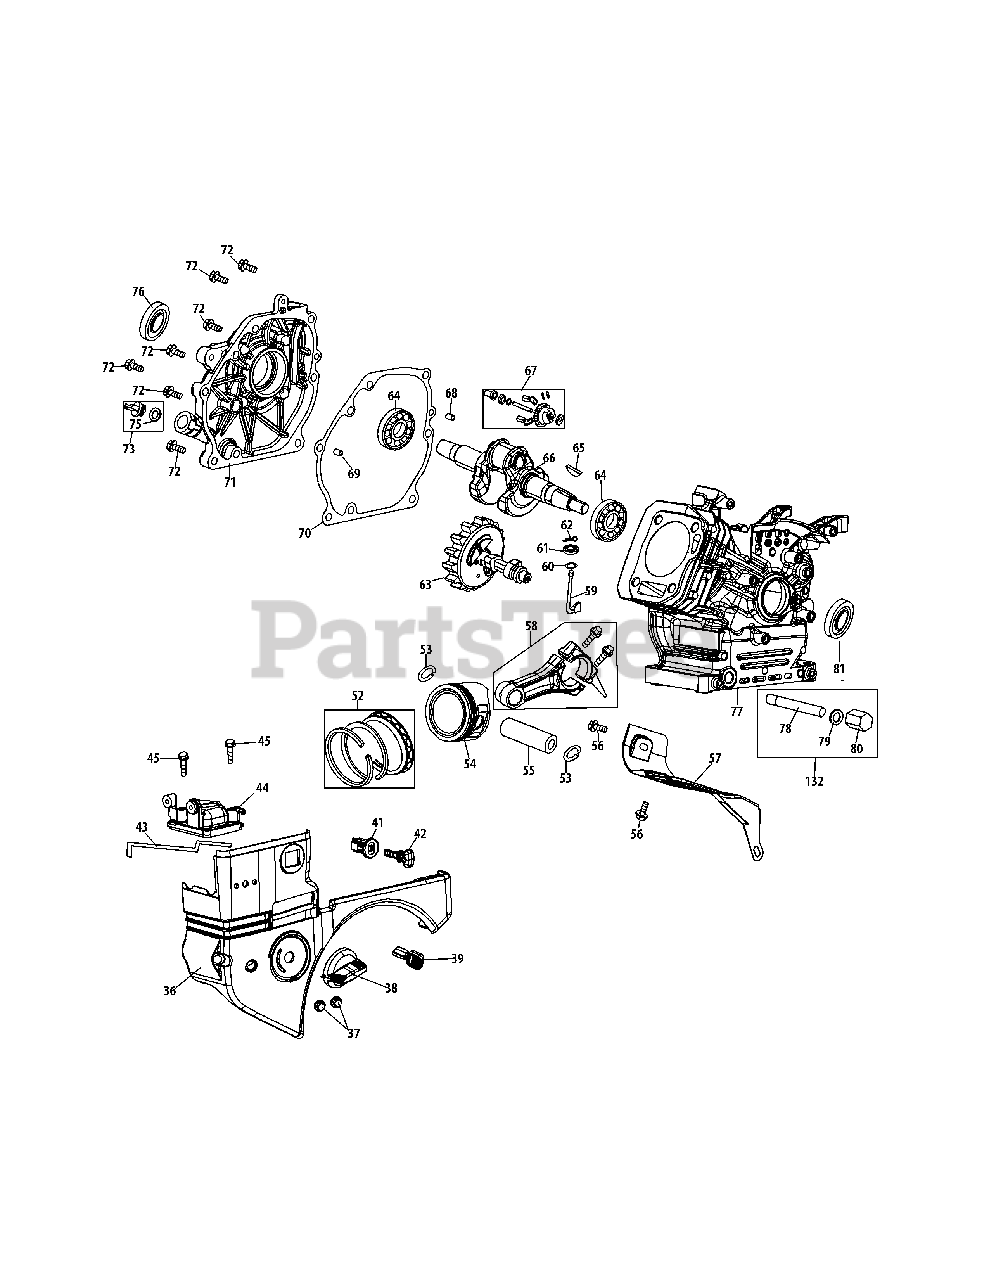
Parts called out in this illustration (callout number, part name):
36	Air Cleaner Housing
38	Choke Knob
39	Throttle Control Knob
41	Key Switch Base
42	Key
43	Choke Push Rod
44	Heater Box
45	Bolt M6×25
52	Piston Ring Set
53	Piston Pin Snap Ring
55	Piston Pin
56	Bolt M6×12
57	Air Shield
58	Connecting Rod Assembly
59	Governor Arm Shaft
60	Washer 5.2×1.9
61	Governor Seal
62	Cotter Pin
63	Camshaft Assy.
64	Radial Ball Bearing, 6205
65	Woodruff Key
66	Crankshaft Assembly
67	Governor Gear/Shaft Assembly
68	Dowel Pin 7×14
69	Dowel Pin 9×14
70	Crankcase Cover Gasket
71	Cover Comp,Left Crankcase
72	Bolt M8×32
73	Oil Fill Plug Asm
75	O-Ring 15.8×2.5
76	Oil Seal,25×41.25×6
77	Short Block
78	Oil Drain Pipe Assy.
79	Washer 10×16×1.5
80	Oil Drain Plug
81	Oil Seal 25×41.25×6
132	Oil Drain Assembly
